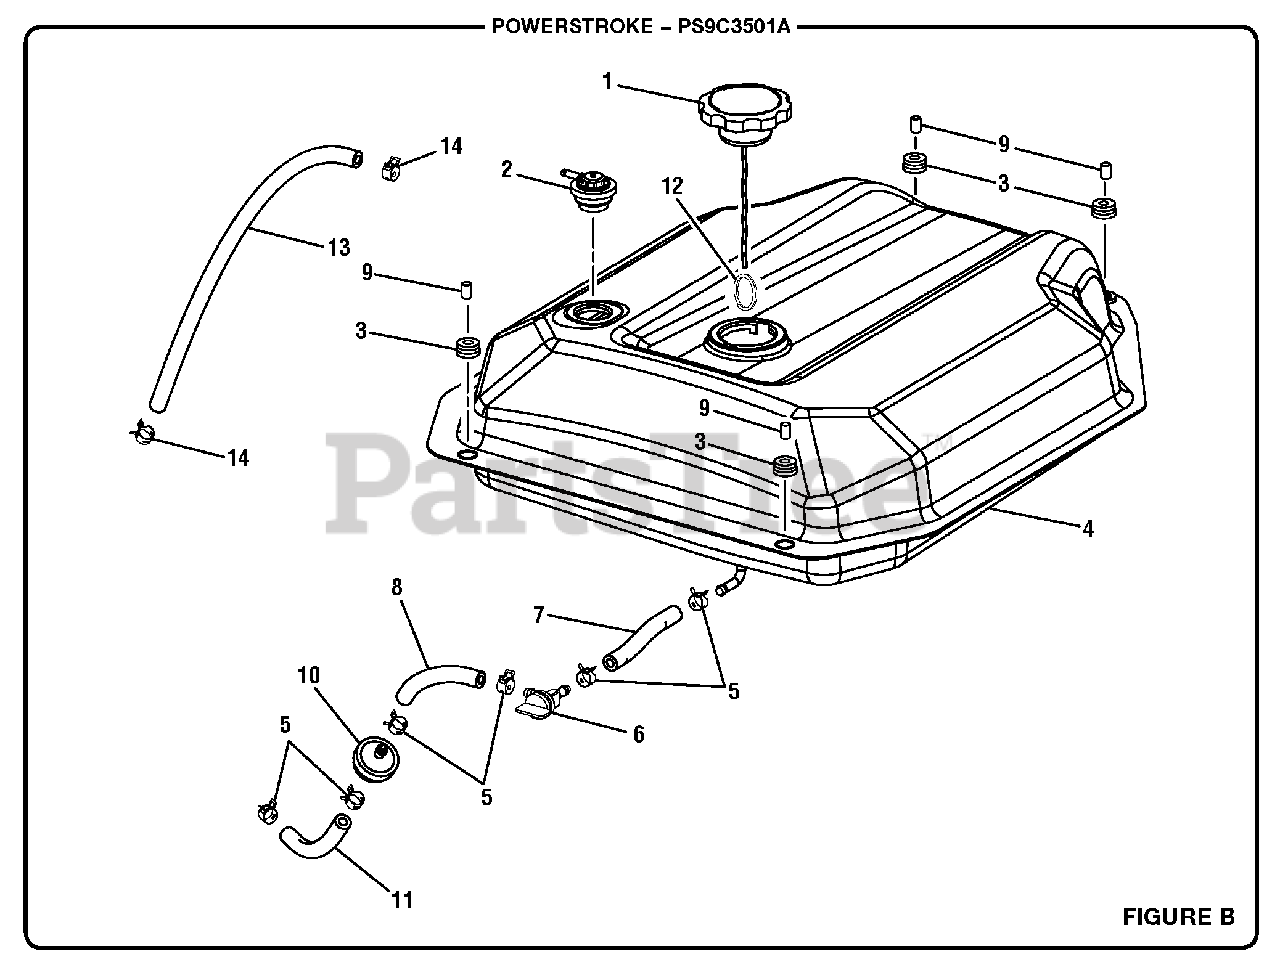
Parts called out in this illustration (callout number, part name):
1	Fuel Tank Cap
2	Fuel Tank Vapor Vent
4	Fuel Tank
5	Fuel Line Clamp (1/2 in.)
6	Fuel Shut Off Valve
7	Fuel Line (90 mm)
8	Fuel Hose (110 mm)
10	Fuel Line Filter
11	Fuel Hose (110 mm)
12	Ring Clip
13	Vent Hose
14	Fuel Line Clamp (7/16 in.)
